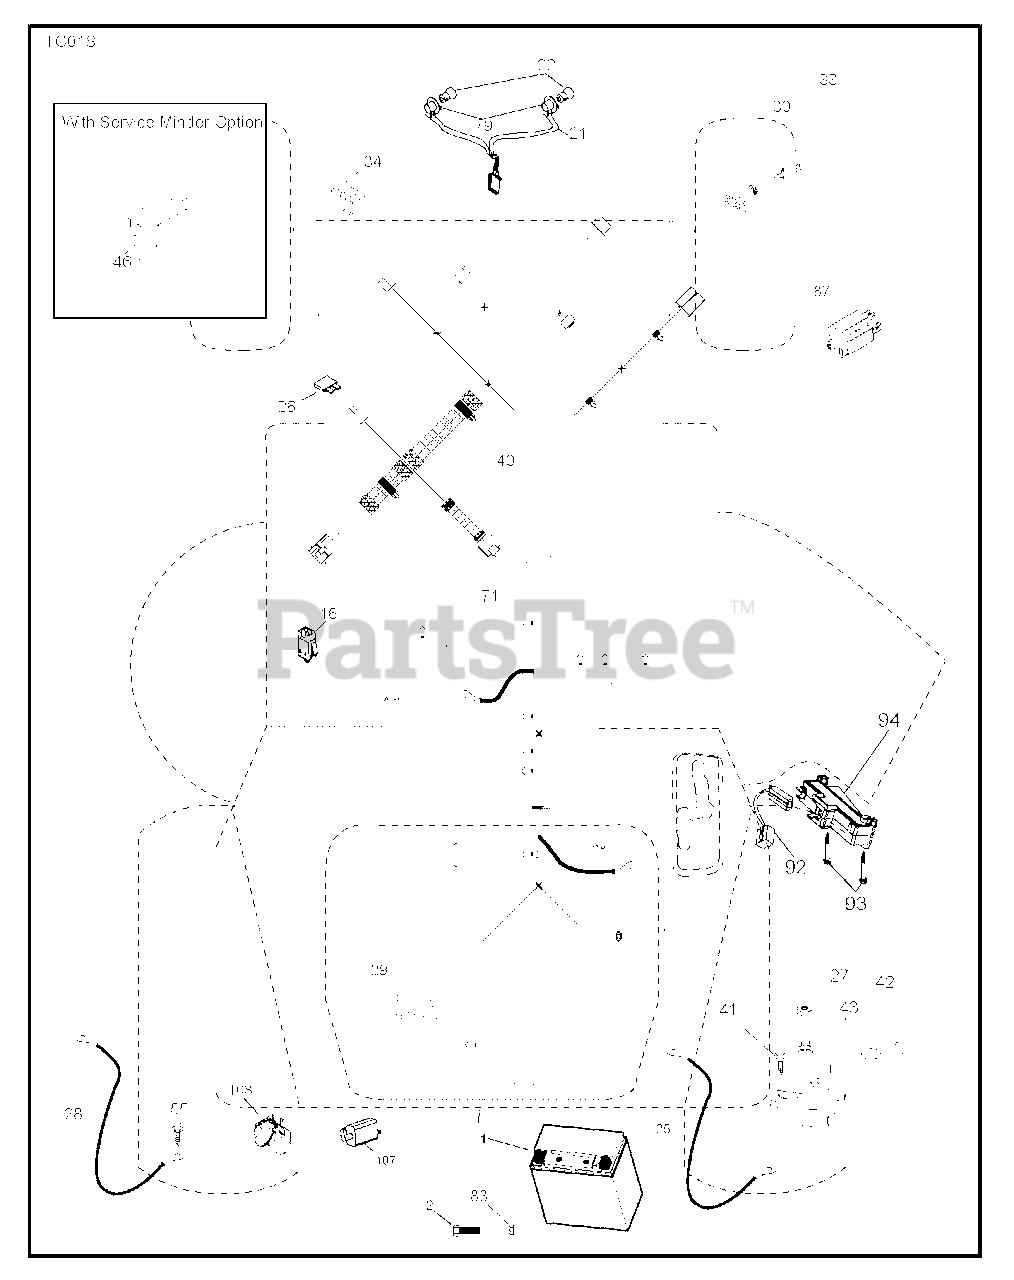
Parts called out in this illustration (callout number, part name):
1	BATTERY BATTERY 14AH 12V LEOC
2	SCREW.HEX.HEAD.CAP.M6 X1.12W
16	SWITCH INTERLOOK PUSH-IN
21	HARNESS.LIGHT W/4152J BULBS
25	CABLE BATTERY CABLE
26	FUSE 20AMP
27	NUT
29	SWITCH.SEAT.DELTA.OPC.
30	SWITCH.IGN.DELTA.W.LGH.ROS
33	KEY.CHAIN.BLISTER.PACK.GEN.INT
40	RP HARNESS.ELECTRICAL.DASH.SRD
41	SCREW
42	TERMINAL COVER
43	SOLENOID.W/BRASS.PLUNGER
55	SCREW 5/16"
79	BULB HOLDER ASM.
83	NUT NUT SQUARE
87	RP SWITCH.RAILMOUNT.NO-NC-NC
92	HARNESS.PIGTAIL.CONSLE
93	SCREW.PLASTITE
94	MODULE.REVERSE.ROS
107	.WITCH.FULL BAGGER.INDICATOR
108	SWITCH.SNAPMOUNT.NC
